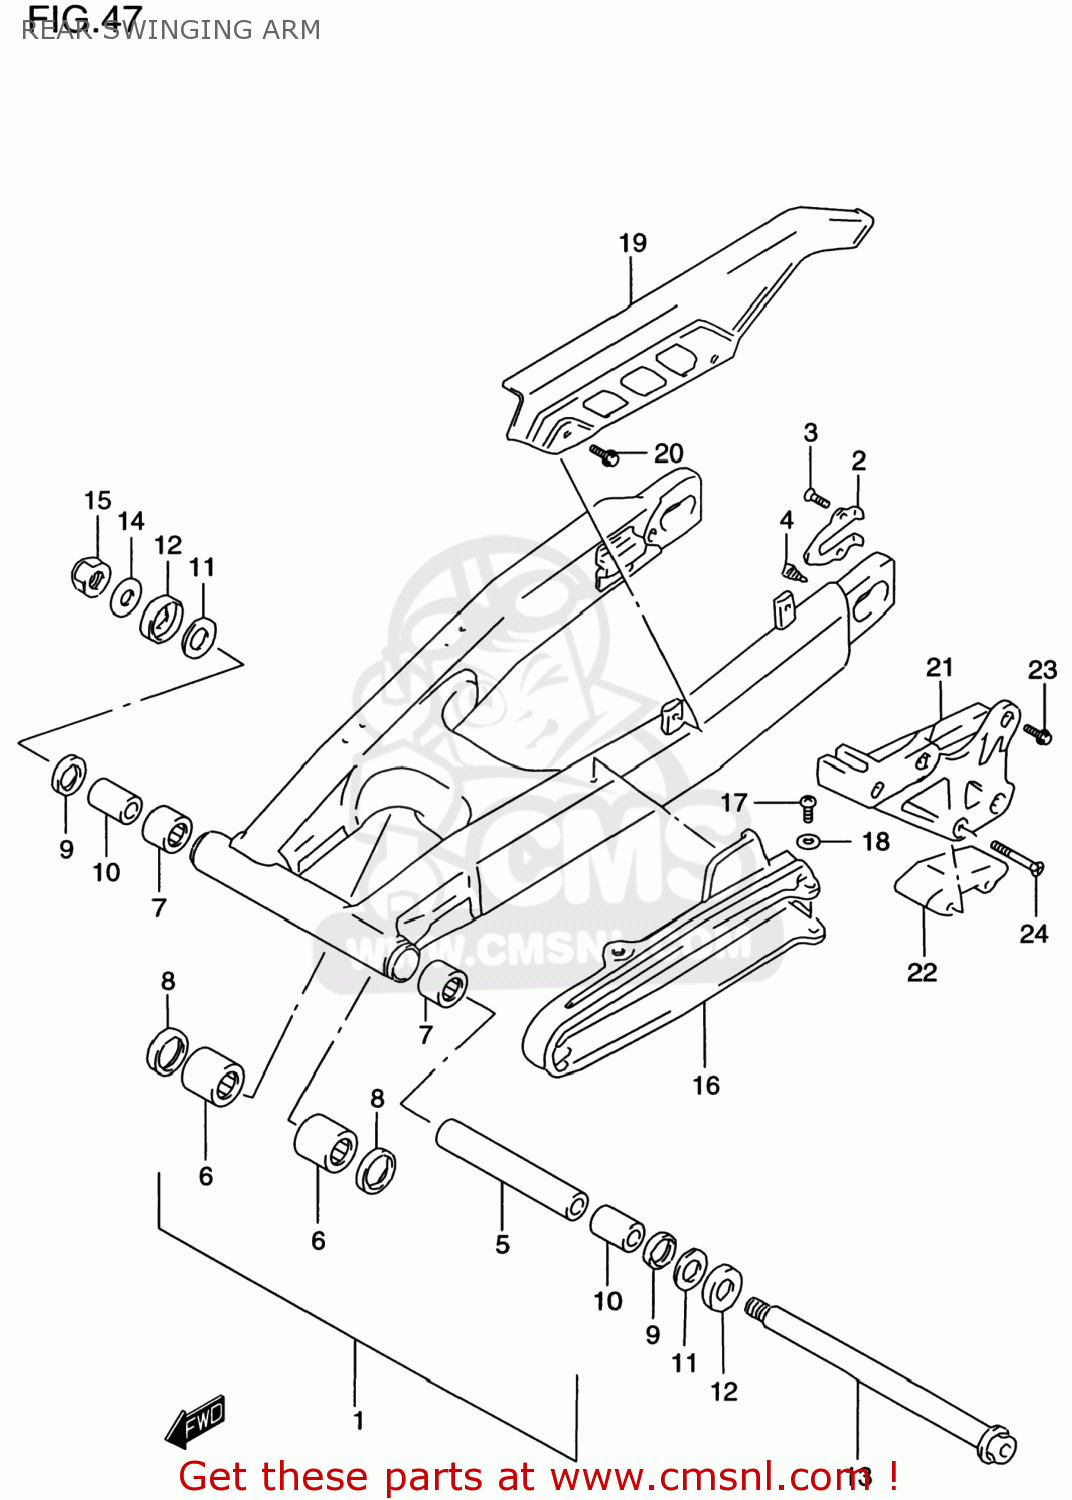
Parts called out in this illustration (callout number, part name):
1	SWING ARM ASSEMBLY,REAR
2	PLATE,RR SWING ARM AXLE
3	SCREW(5X8)
4	STOPPER,CHAIN ADJUSTER
5	SPACER,SWGARM PIVOT CTR
6	BEARING(20X27X23.5)
7	BEARING(22X29X30)
8	SEAL,OIL(20X27X5)
9	SEAL,OIL(22X29X4)
10	SPACER,SWGARM PIVOT BRG
11	WASHER
12	COVER,SWINGINGARM PIVOT
13	AXLE,RR
14	WASHER, FIXED DRIVE FACE
15	NUT
16	BUFFER,CHAIN TOUCH DEFENSE
17	SCREW 6X12
18	WASHER
19	CASE,CHAIN
20	BOLT(6X10)
21	GUIDE,CHAIN
22	DEFENSE,CHAIN GUIDE
23	BOLT
24	SCREW
